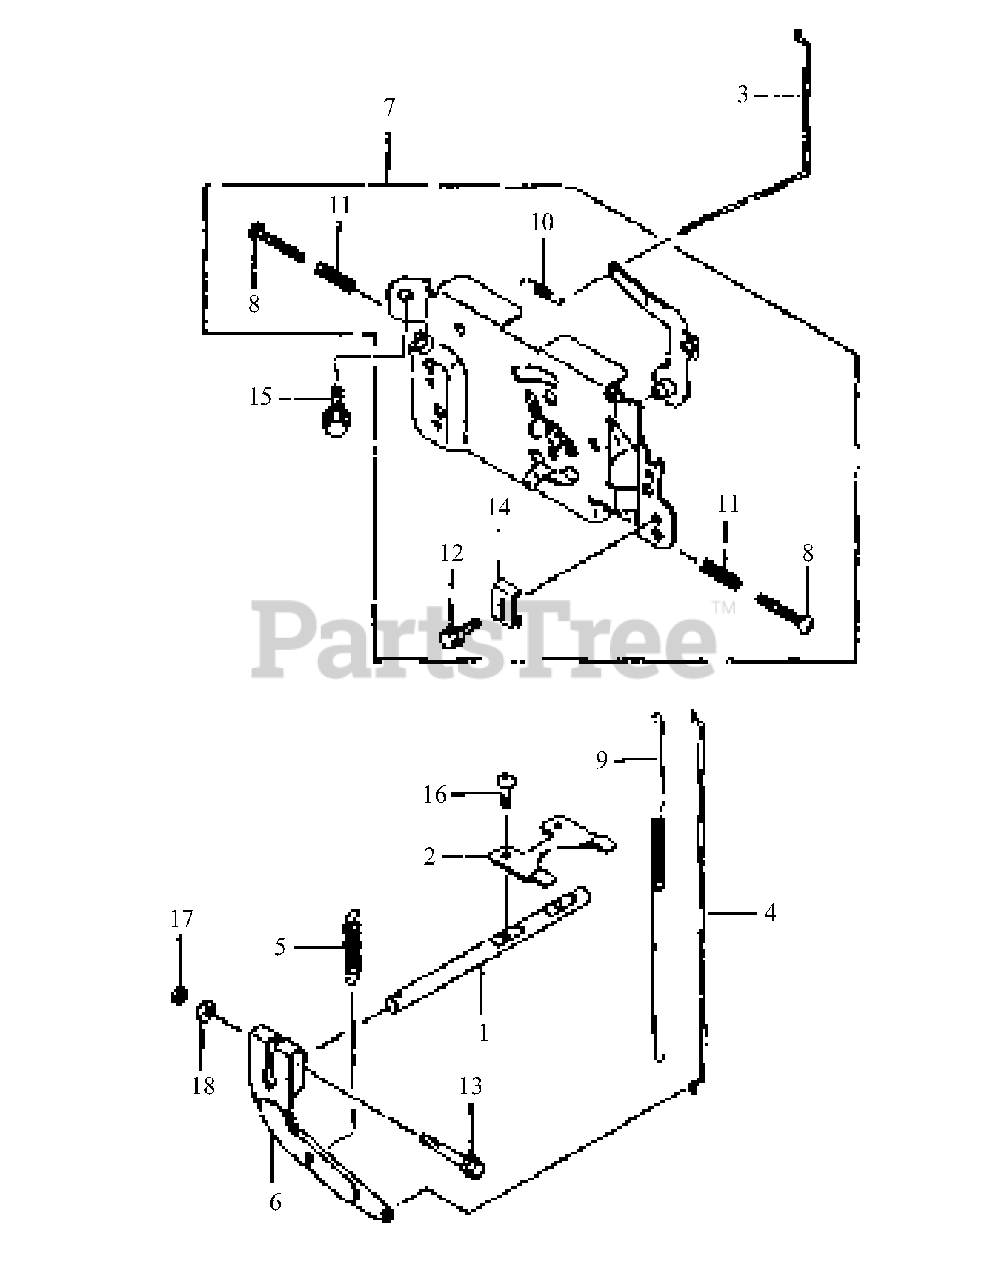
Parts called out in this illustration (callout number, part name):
5	Spring, Governor
6	Arm, Governor
7	Panel, Control
10	Spring
15	Bolt, Flange
18	Washer, Plain
